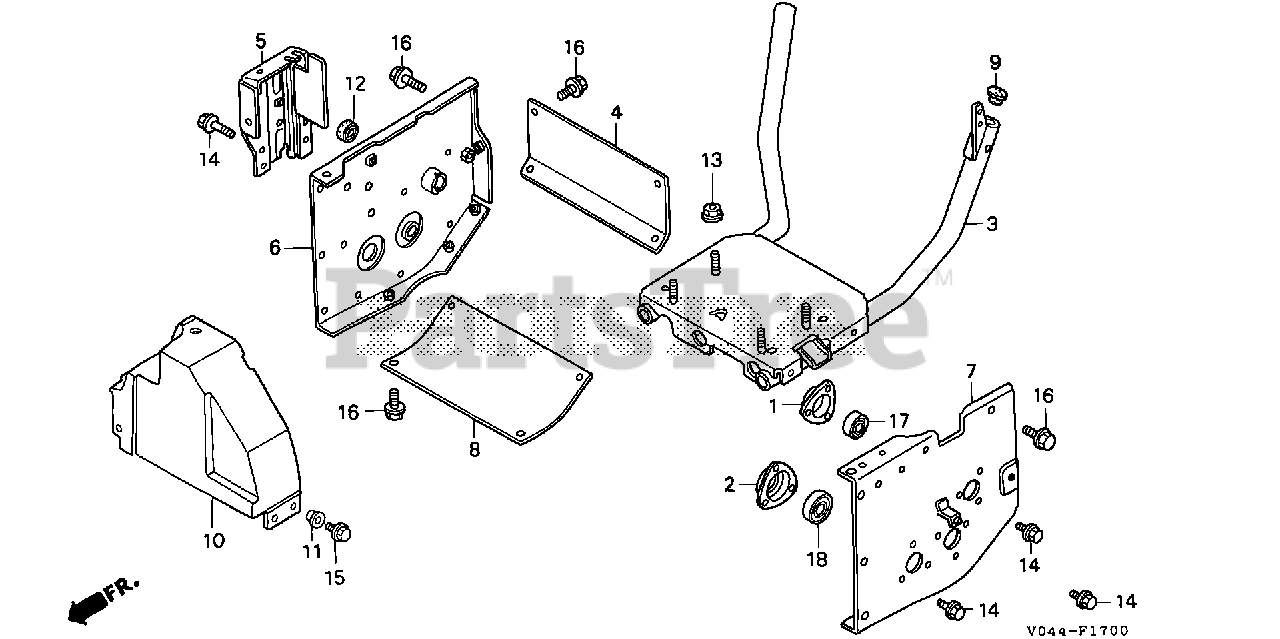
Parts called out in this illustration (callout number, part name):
1	HOLDER, BEARING
2	HOLDER, WHEEL SHAFT BEARING
3	BED, ENGINE
4	STAY, ENGINE BED
5	HOLDER, WIRE
6	STAY, R. ENGINE BED
7	STAY, L. ENGINE BED
8	STAY, ENGINE BED (B)
9	CAP, HANDLE (LOWER)
10	COVER, BELT
11	WASHER, CHAIN CASE SETTING
12	COVER, DUST (28MM)
13	NUT, FLANGE (8MM)
14	BOLT, FLANGE (6X12)
15	BOLT, FLANGE (6X14)
16	BOLT, FLANGE (8X12)
17	BEARING, RADIAL BALL (6004UU)
18	BEARING, RADIAL BALL (6201UU)
